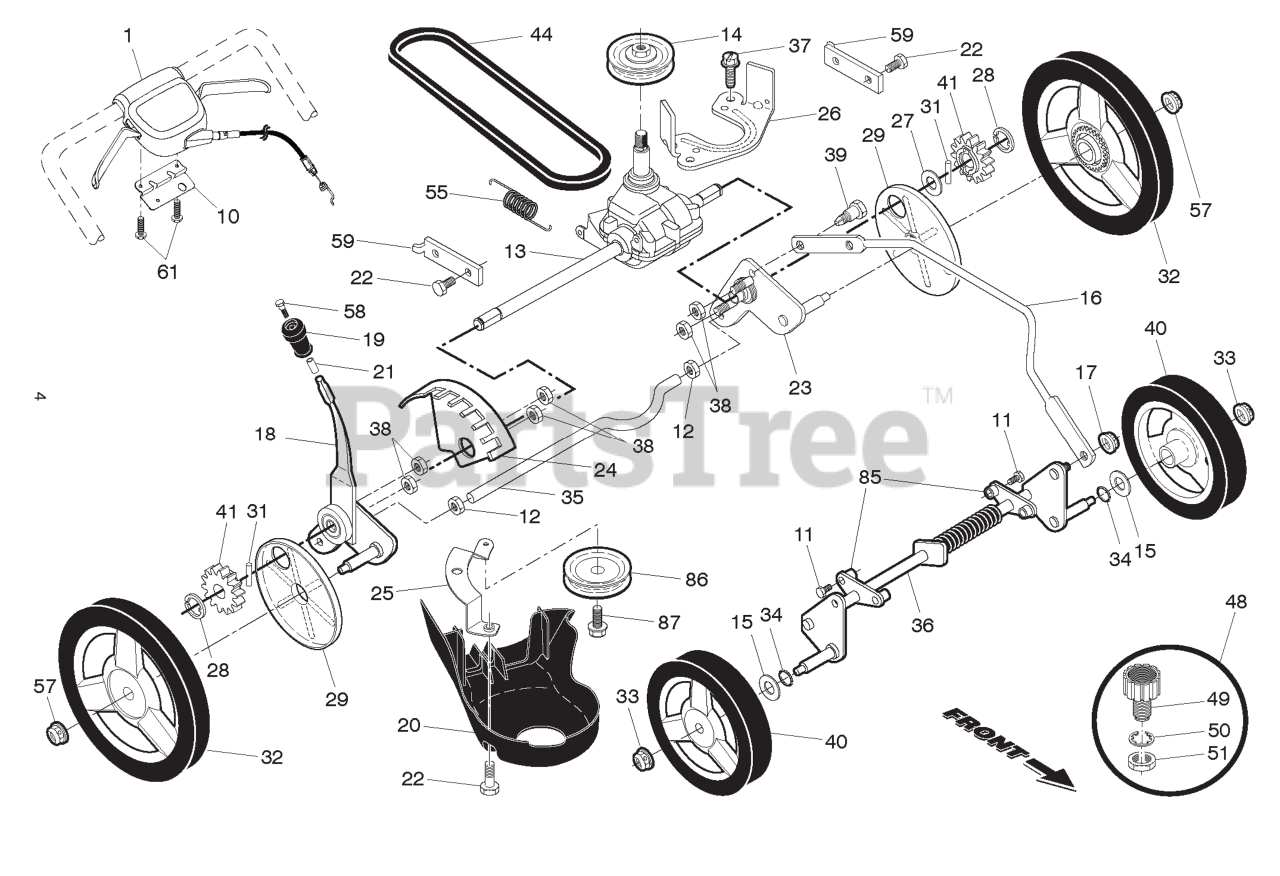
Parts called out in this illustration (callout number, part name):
1	CONTROL.DR.AW2.22+.BLK.GEN
10	BRACKET DUAL TRIGGER CONTROL
11	SCREW.HX.13X.750
12	NUT.HEX.1/2-20
13	TRANSMISSION.22+AWD.WALK.MOWER
14	PULLEY.DRIVE.SM.AWD/RWD
15	WASHER.FLAT.1/2
16	ROD.CONNECTING.RGD.22+.HW.BLAC
17	NUT.LOCK.5/16-18
18	KIT.SEL.ASM.22+RG.11"HW.BLKNB
19	KNOB.SEL.SPRING.22+.SP.RIB.BLK
20	COVER.REAR.DRIVE.22+2013
21	SCREW.PLASTIC.ANCHOR.5/16
22	BOLT.5/16HEX.WHS.HD
23	ADJUSTER.ARM.ASM.LT.SP.HW.BZP
24	BRACKET.WHL.ADJ.9.POS.W/PAD
25	BRACKET.DRIVE.COVER.RGD.
26	BRACKET.TRANS.BELTKEEP.21 RWD
27	WASHER
28	E-RING 7/16 RE
29	COVER.DUST.WHEEL.RGD.HW.NEW
31	PAWL, DRIVE
32	RP_WHEEL.11.RAD3.460.BB2.NEW.H
33	NUT.HEX.FLANGE.3/8-16.LO(3 2)
34	O-RING..070X.487.NEOPRENE
35	AXLE.REAR.RGD
36	AXLE.ASM.FRT.RGD.BZP
38	NUT.HEX.FLANGE.1/4
39	SHOULDER BOLT SEMI GIMLET PT.
40	WHEEL & TIRES ASSY, FRONT
41	PINION.12.TEETH.RGD.22+HW
44	BELT V3L 35.42, CLUTCHING COVE
48	KIT.WASH-OUT.PORT
49	FITTING, HOSE, WATER WASHOUT
50	WASHER.LOCK.INTERNAL.TOOTH
51	LOCKNUT.HEX.WITH.O-RING
55	SPRING.RETURN.AUTO.
57	NUT.HEX.FLANGE.3/8-16.LOCKNUT
58	SCREW.12-14X1.500
59	BRACKET.SUPPORT.22+RWGD.BZP
61	SCREW, PHILLIPS HEAD 10 X 5/8
85	BRACKET.FRT.AXLE.SUPPORT
86	PULLEY.RWD.IDLER.DBL SEAL
